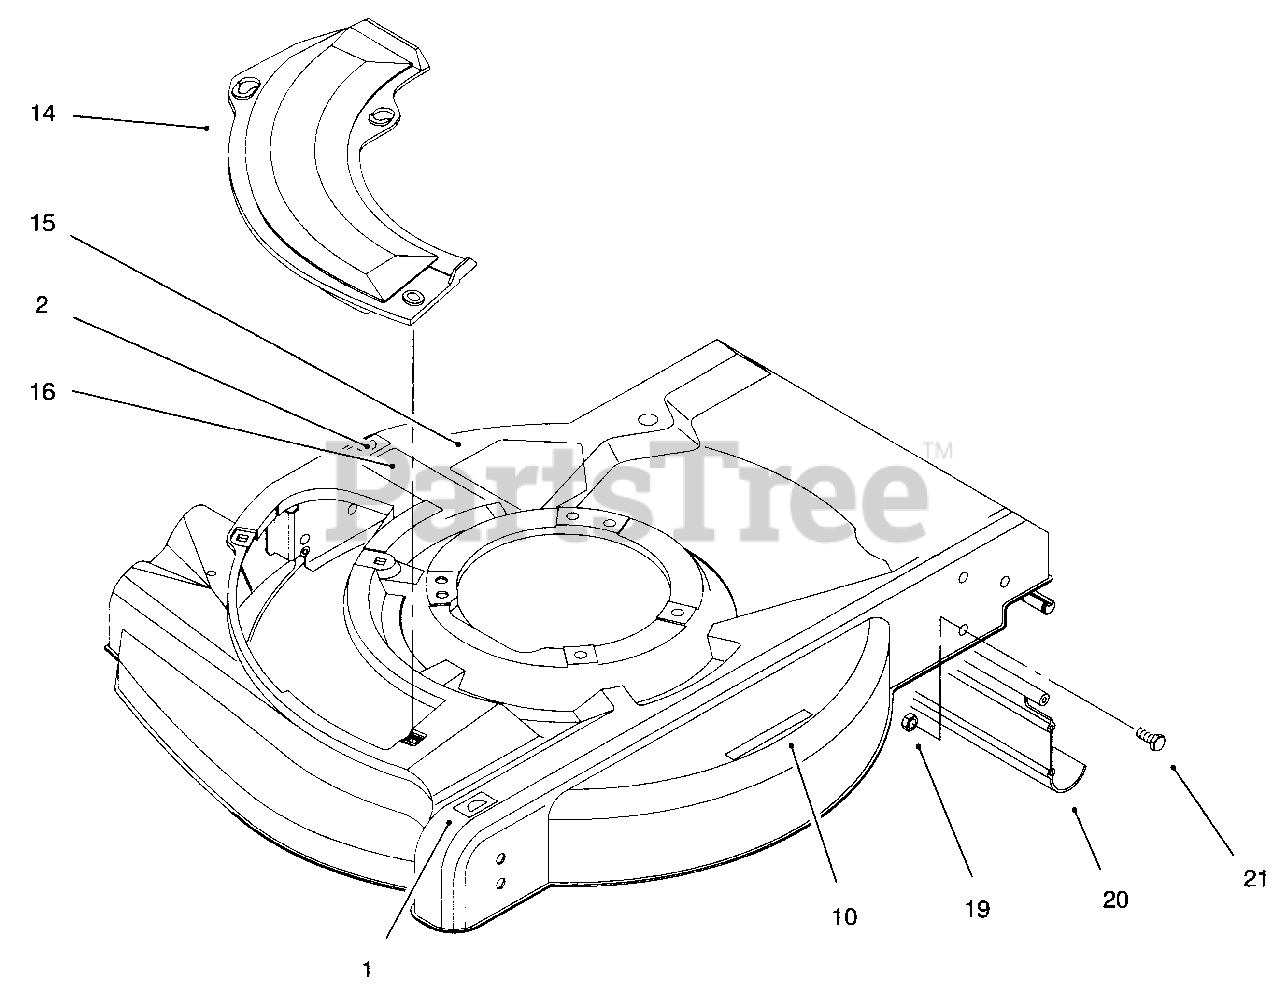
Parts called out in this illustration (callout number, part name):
1	Decal-H.O.C.
2	Decal-H.O.C.
10	Decal-Warning
14	Plate-Cover
15	Decal-Danger
16	Decal-Discharge
19	Nut-Lock
20	Shield-Trailing
21	Screw-Hex Hd. Cap
